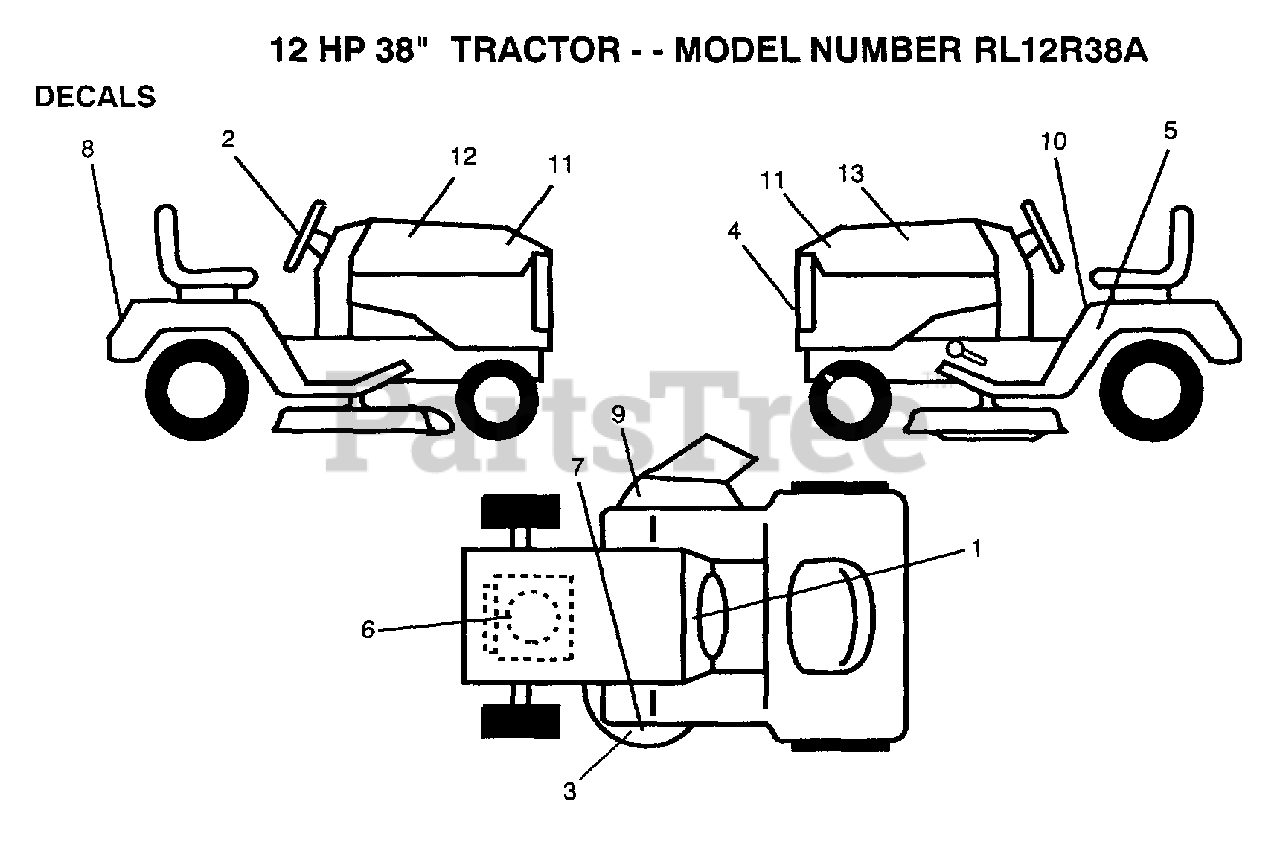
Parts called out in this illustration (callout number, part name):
2	"DECAL,STR WHL"
4	GRILL DECAL
5	IND HGT DECK DECA
6	DECAL.ENG.271967
7	DECAL YT
8	FENDER DECAL
9	DECAL WARNING
10	DECAL CAUTION
11	"DECAL,HOOD"
12	"DECAL,STP HD RH"
13	"DECAL,STP HD LH"
